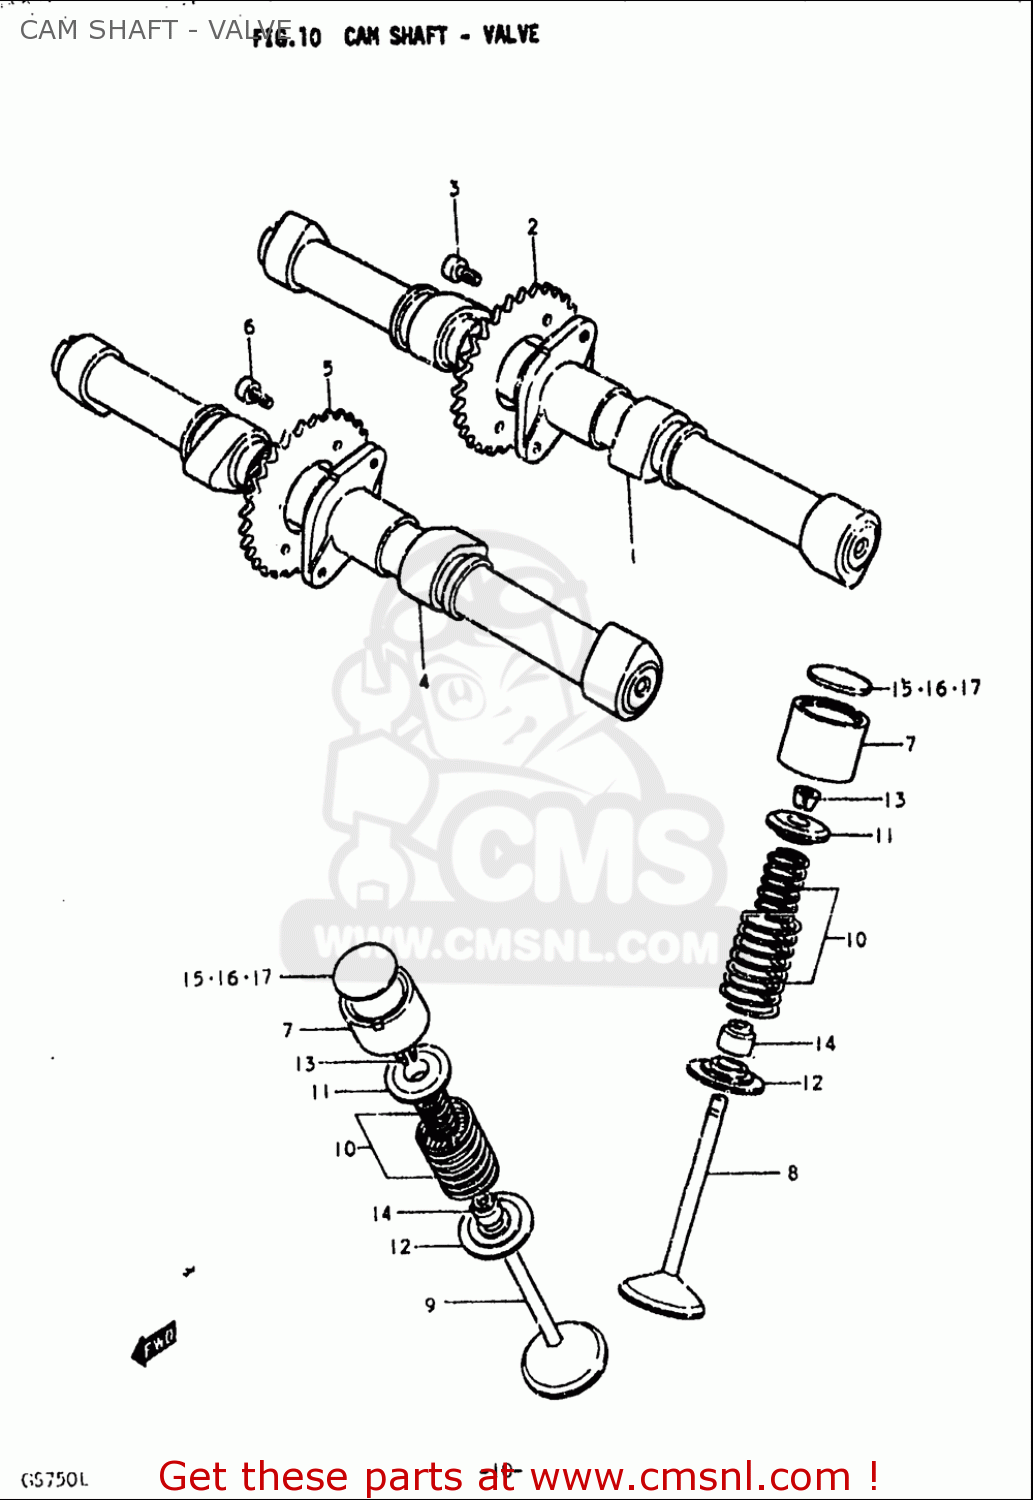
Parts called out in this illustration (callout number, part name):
2	SPROCKET,CAMSHAFT INTAKE
3	BOLT,VAC.PIPE
5	SPROCKET,EXHAUST CAM(NT:30)
6	BOLT,VAC.PIPE
7	TAPPET,INTAKE
8	VALVE,INTAKE
9	VALVE,EXHAUST
10	SPRING SET,VALVE
11	RETAINER,VALVE SPRING
12	SEAT,VALVE SPRING
13	COTTER VALVE
14	SEAL,OIL(7X14.4X9)
15	SHIM,TAPPET(T:2.15)
16	SHIM,TAPPET(T:2.60)
17	SHIM,TAPPET(T:3.05)
18	SHIM SET,TAPPET
19	CASE,SHIM
